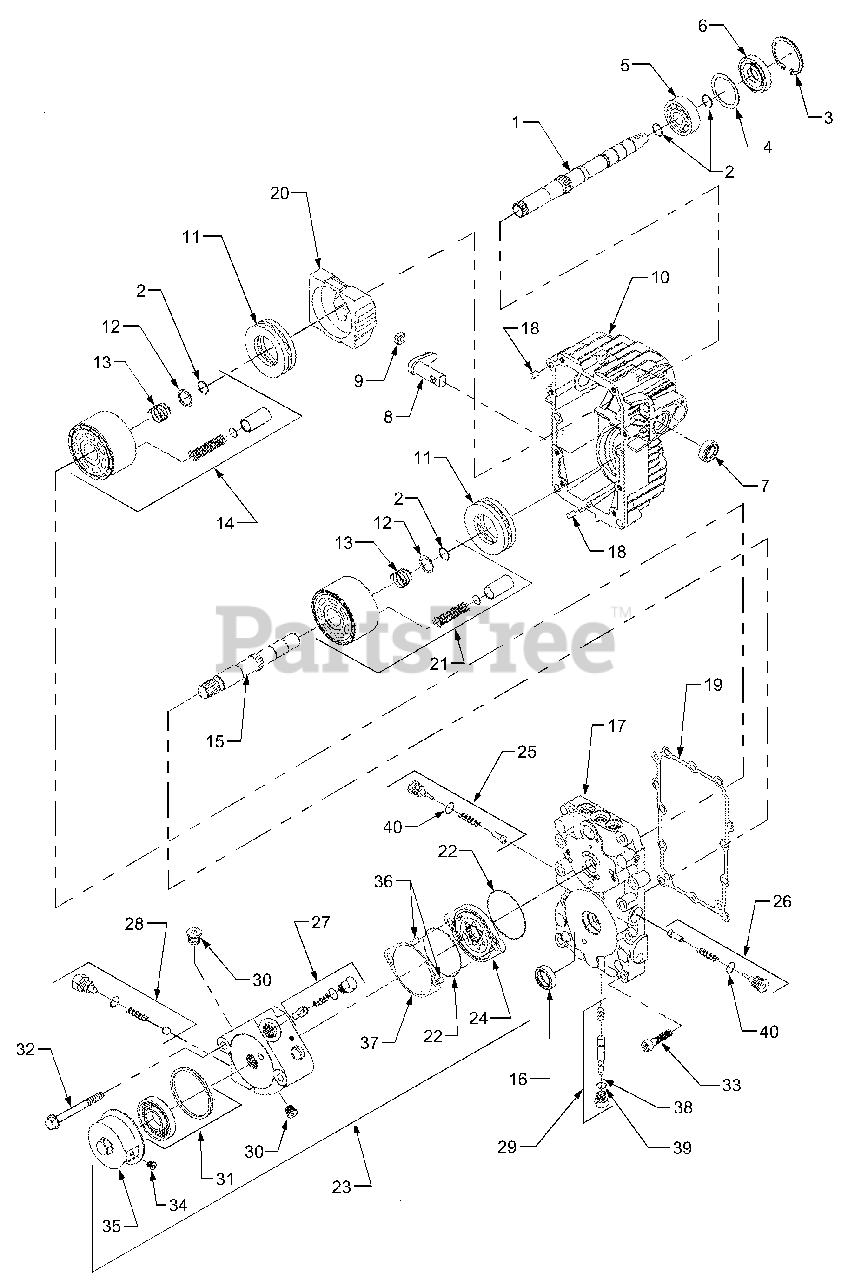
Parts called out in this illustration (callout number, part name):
1	Shaft, Pump
2	Ring, Wire Retaining
3	Ring, Retaining
5	Bearing, Ball
6	Seal, Lip
8	Arm, Trunnion
9	Guide, Slot
10	Housing Assembly
11	Bearing Assembly, Thrust Ball
12	Washer, Block Thrust
13	Spring, Block
14	Kit, Pump Cylinder Block
15	Shaft, Motor
16	Not Used In This Application
17	Kit, Center Section
19	Gasket, Center Section
20	Swashplate, Variable
21	Kit, Motor Cylinder Block
23	Kit, Auxiliary Charge Pump
24	Gerotor & Housing Assembly
25	Kit, Check Valve
26	Kit, Check Valve w/ .044 Orifice
27	Kit, Check Relief
28	Kit, Auxiliary Relief Valve
29	Kit, Bypass Valve
31	Kit, Auxiliary Filter
32	Screw, Flange Head Cap, M8 x 60
33	Screw, Socket Head Cap
35	Cover, Filter
37	Shim, Charge Pump
38	O-Ring
39	O-Ring
40	O-Ring
